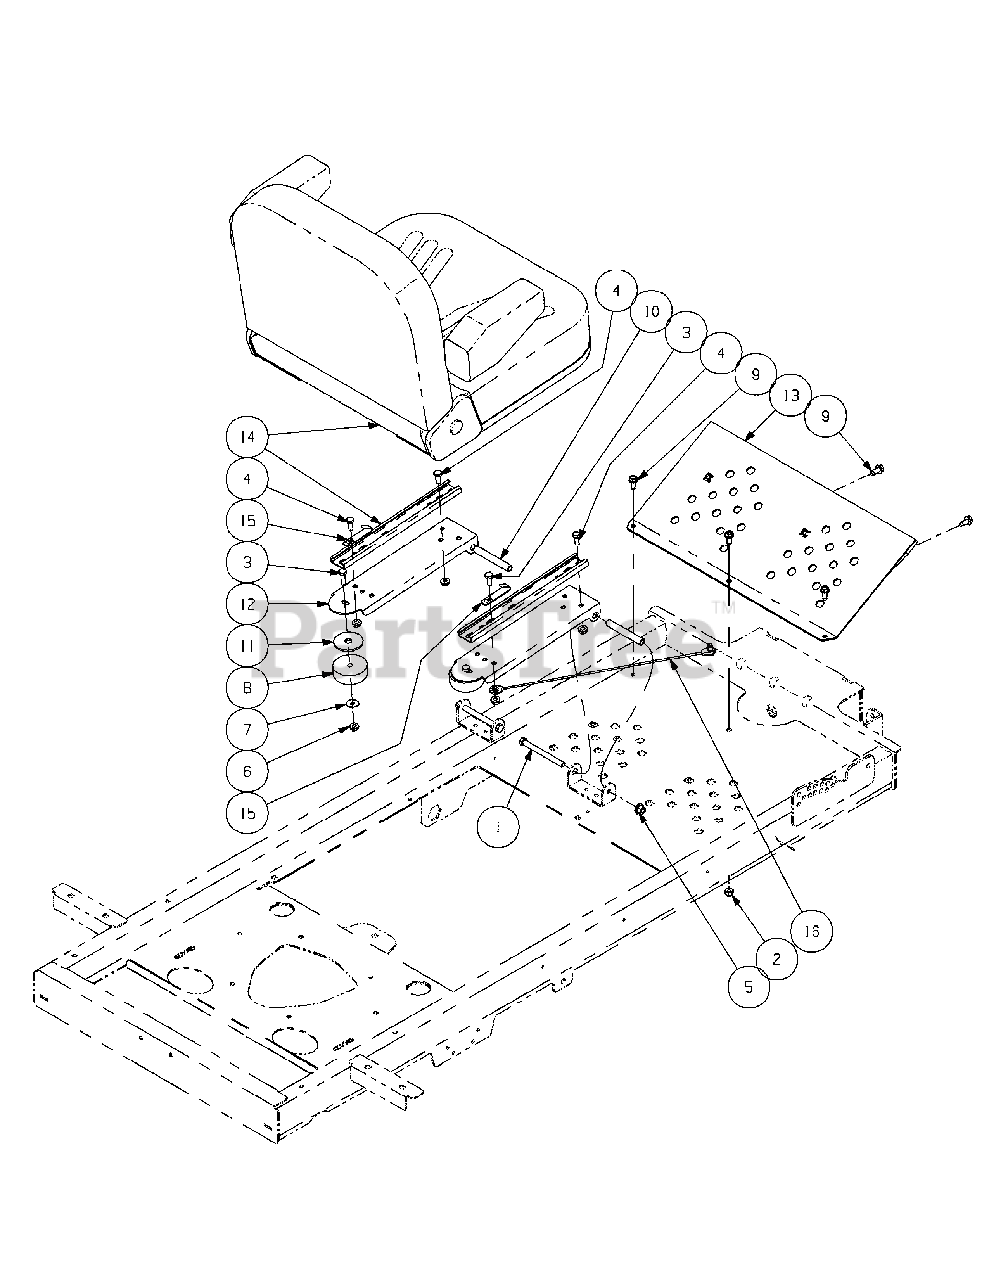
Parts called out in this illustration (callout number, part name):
1	Hex Cap Screw, 3/8-16, 4.00
2	Nylock Nut, 5/16-18
3	Hex Cap Screw, 5/16-18 x 1.0
4	Hex Cap Screw, 5/16-18 x .75
5	Flange Lock Hex Nut, 3/8-16
6	Nut, 5/16-18, Hex Flange Lock
7	Belle Washer, .325 x .930 x .045
8	Grommet, 2.5 OD x 1.0 Long
9	Self Tapping Screw 5/16-18 x .750
10	Spacer, .370 ID x .500 OD x 3.45
11	Washer, .531 ID x 2.13 OD x .134
12	Seat Mounting Bracket
13	Foot Rest Bracket
14	Seat includes:
15	Seat Stop Bracket
16	Lift Cable
